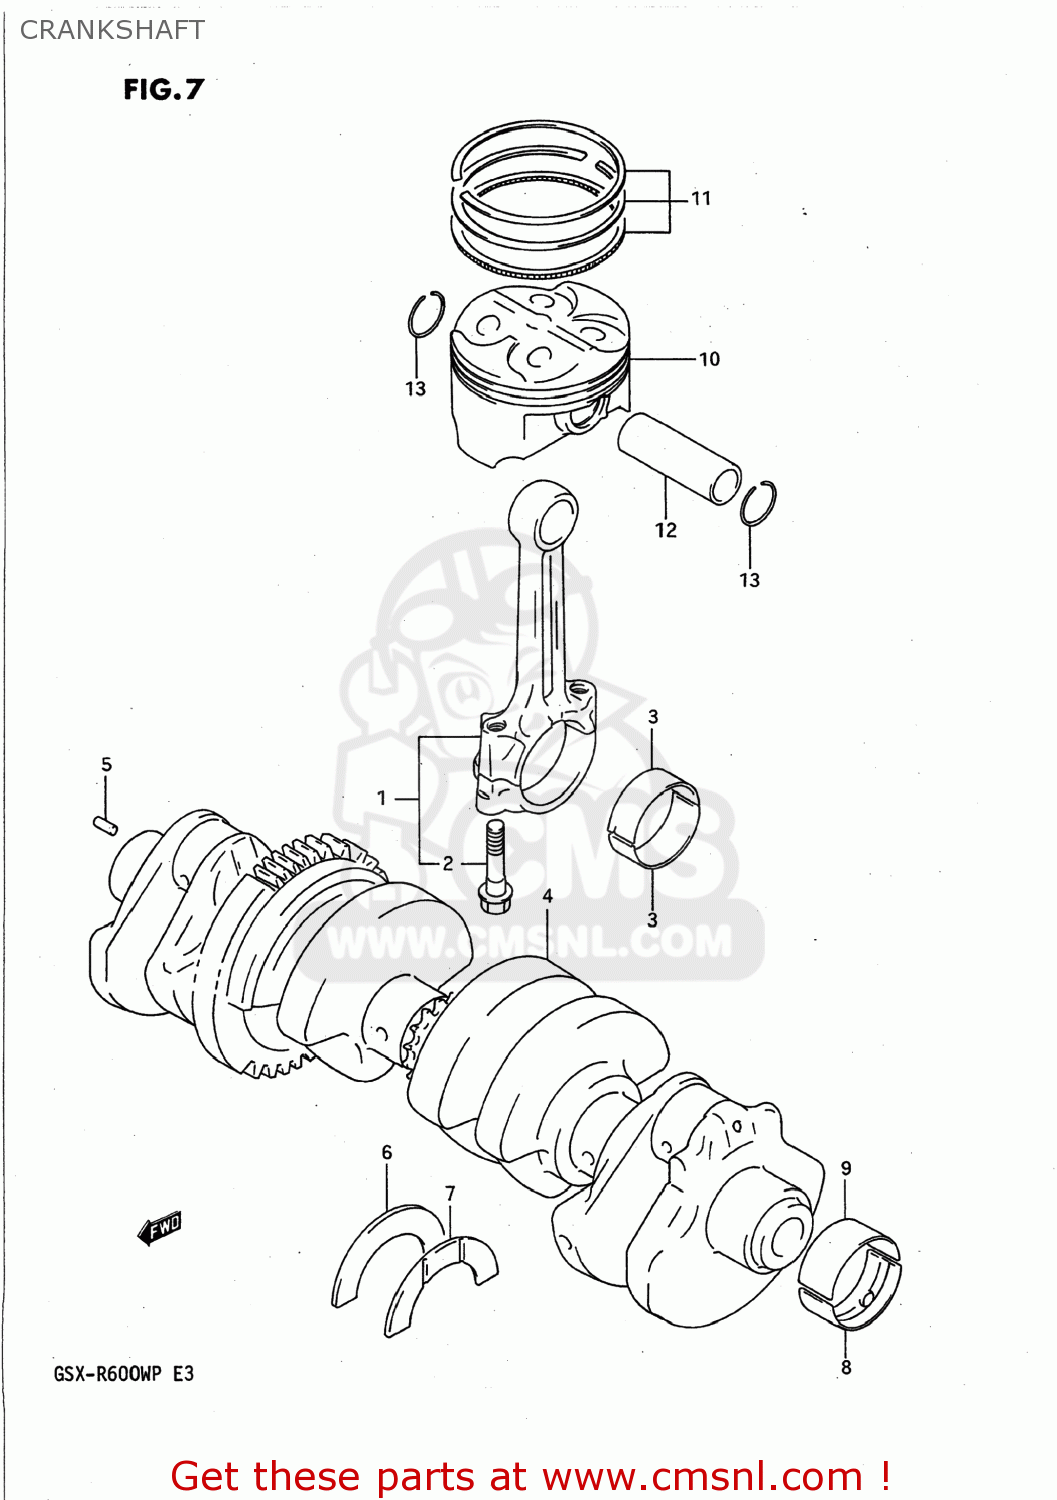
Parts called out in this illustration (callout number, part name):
1	CONNECTING ROD ASSY
2	BOLT,CONNECTING ROD
3	BEARING,CRANK PIN
4	CRANKSHAFT SET
5	PIN
6	BEARING,CRANK THRUST(GREEN)
7	BEARING,CRANK THRUST(RED)
8	BEARING,CRANKSHAFT(GREEN)
9	BEARING,CRANKSHAFT(GREEN)
10	PISTON
11	RING SET,PISTON
12	PIN,PISTON
13	RING,SNAP 16MM
